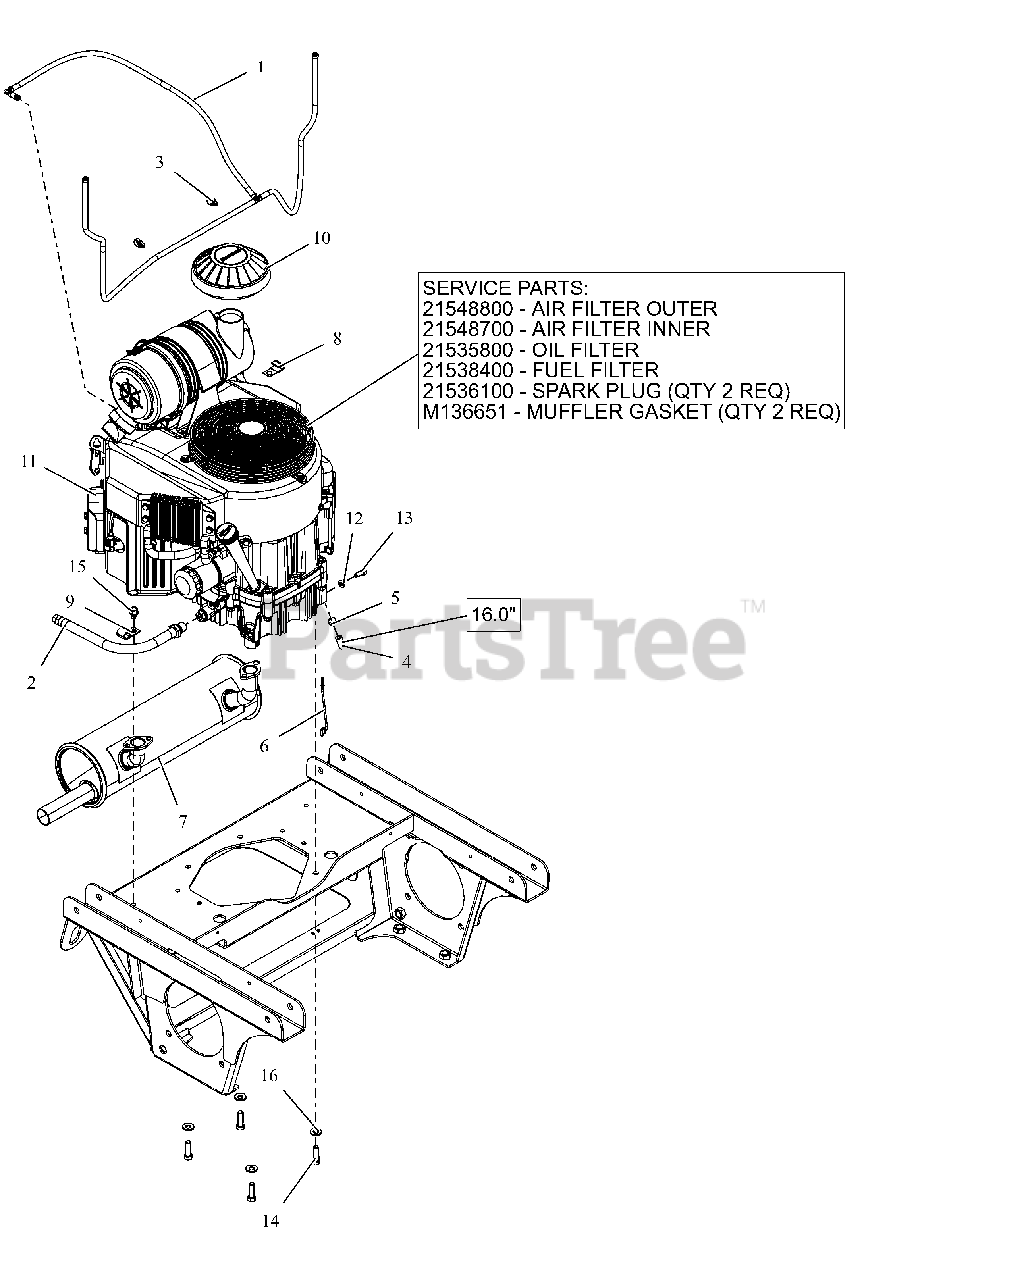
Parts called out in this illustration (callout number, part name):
1	ASM, VAPOR LINE
2	HOSE, OIL DRAIN
3	ROUTING CLIP (1/2" ID)
4	HOSE, .25 LOW-PERM BULK GAS
5	CLAMP, FUEL LINE
6	LEAD - STARTER SOLENOID
7	MUFFLER, 27-31 KAW
10	CAP, AIR CLEANER INTAKE (2")
11	ENGINE, KAWASAKI FX850
11	FILTER, OUTER
11	FILTER, INNER - KAW
11	FILTER,OIL - KAW
11	FUEL FILTER - KAWASAKI
11	PLUG, SPARK
11	GASKET, MUFFLER #
12	WSHR,LK-REG .312X.078 ZCC
13	BLT, HEX M8-1.25X20 G8.8 ZCC
14	BLT, HEX .38-16X1.25 G5 ZCC NT
15	SCR,TAP .375-16X.50 HWH TR ZCC
16	WASHER, 3/8" SPRING DISC
